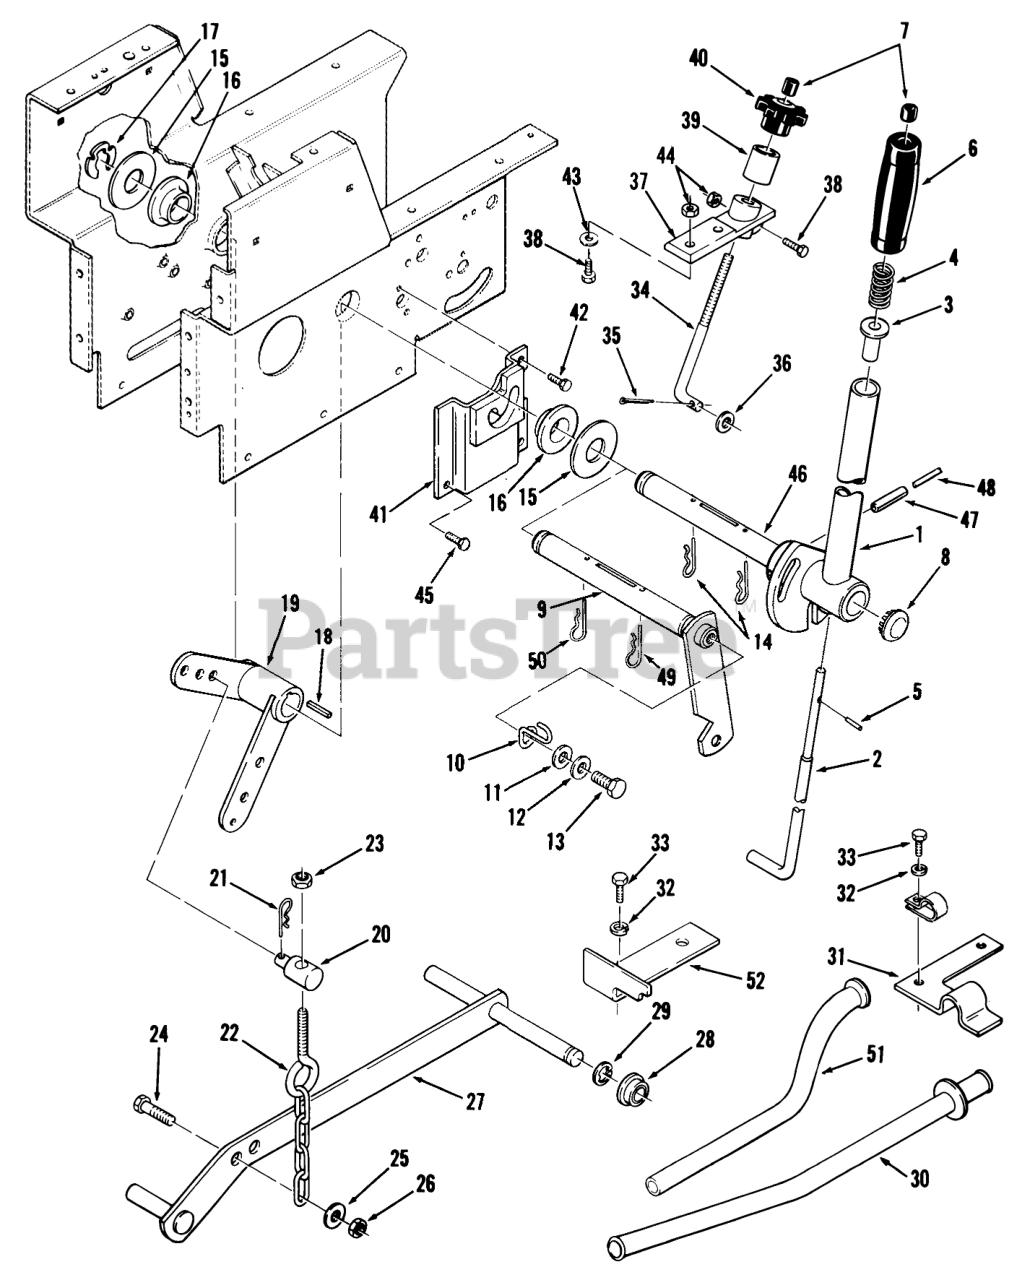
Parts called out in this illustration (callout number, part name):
1	Lift Lever
2	ROD-LATCH LIFT
3	RETAINER-SPRING
4	SPRING-COMPRESSION
5	PIN-SPIROL
6	HANDGRIP
7	CAP-ROD, PLUNGER
8	PLUG
9	Lift Lever
10	Indicator
11	WASHER 5/16 SAE
12	Lockwasher
13	Screw
14	Pin-Cotter
15	WASHER
16	BEARING-FLANGE
17	Retainer
18	KEY-SQUARE
19	Bellcrank
20	Trunnion
20	TRUNNION-LIFT
21	Hairpin
22	CHAIN-LIFT
23	Nut
24	Bolt
25	WASHER 5/16 SAE
26	Nut
27	ASSY LIFT BAR R
28	BUSHING
29	E Ring
30	TUBE ASSY COMPLET R
31	Clamp-Tube
32	LOCKWASHER
33	Bolt
34	Rod
35	Pop Rivet
36	WASHER -4
37	Casting
38	Bolt
39	Sleeve
40	KNOB-LIFT CONTROL
41	Latch Bracket
42	SCREW
43	WASHER 5/16 SAE
44	Nut
45	Bolt
46	SHAFT-LIFT LEVER
47	SPIROL PIN
48	Roll Pin
49	Hairpin
50	Pin-Cotter
51	TUBE-CONDUIT R
52	Clamp-Tube
